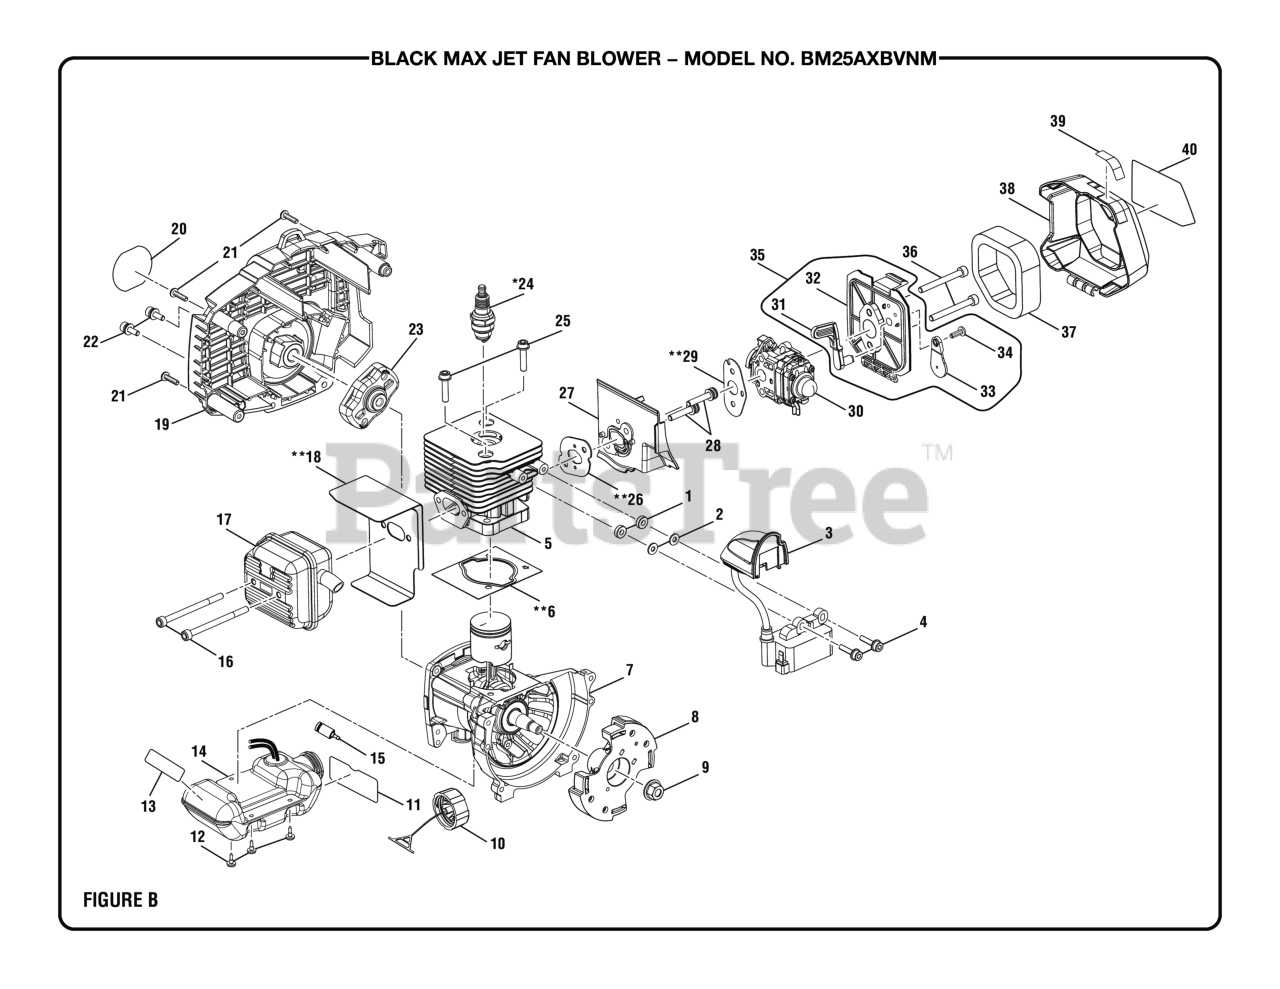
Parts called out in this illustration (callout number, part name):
1	Phenolic Spacer (Ignition Module)
2	Flat Washer (OD10 x ID42 x 1t)
3	Ignition Module
4	Screw (M4 x 22 mm, T20 Torx Slotted Recessed Pan Hd.)
7	Crankcase Assembly
9	Flange Nut (M8, Flywheel)
10	Fuel Cap Assembly (Inc. Tether)
11	FUEL MIXTURE LABEL
12	Shoulder Screw w/Washer (M4 x 14 mm, T25 Torx Truss Hd.)
13	Warning Label (Combustion)
14	Fuel Tank w/Cap Assembly
15	Fuel Filter
16	Cap Screw (M5 x 65 mm, T25 Torx Soc. Hd.)
17	Muffler Assembly
18	Muffler Gasket
19	Rear Housing and Starter Assembly
20	Logo Label (Rear)
21	Screw (M4 x 1.41 mm x 18 mm, T20 Torx Pan Hd. T.F)
22	Cap Screw w/Washers (M5 x 16 mm, T25 Torx Soc. Hd.)
23	Starter Cup
24	Spark Plug (Champion RCJ6Y)
25	Screw (M5 x 22 mm, T25 Torx Soc. Hd.)
26	Heat Dam Insulator
28	Screw w/Washers (M5 x 30 mm, T25 Torx Pan Hd.)
29	Gasket Carb-Heat Dam
30	Carburetor Assembly
31	Choke Lever
32	Air Box Base
33	Screw (M4 x 12 mm, T20 Torx Pan Hd. S.T.)
34	Screw (M4 x 12 mm, Slotted Recessed Pan Hd.)
35	Airbox Assembly (Inc. Key Nos. 31-34)
36	Cap Screw (M5 x 45 mm, T25 Torx Soc. Hd.)
37	Air Filter (Element)
38	Air Box Cover (Inc. Key Nos. 39-40)
39	Choke Position Label
40	Starting Instructions Label
